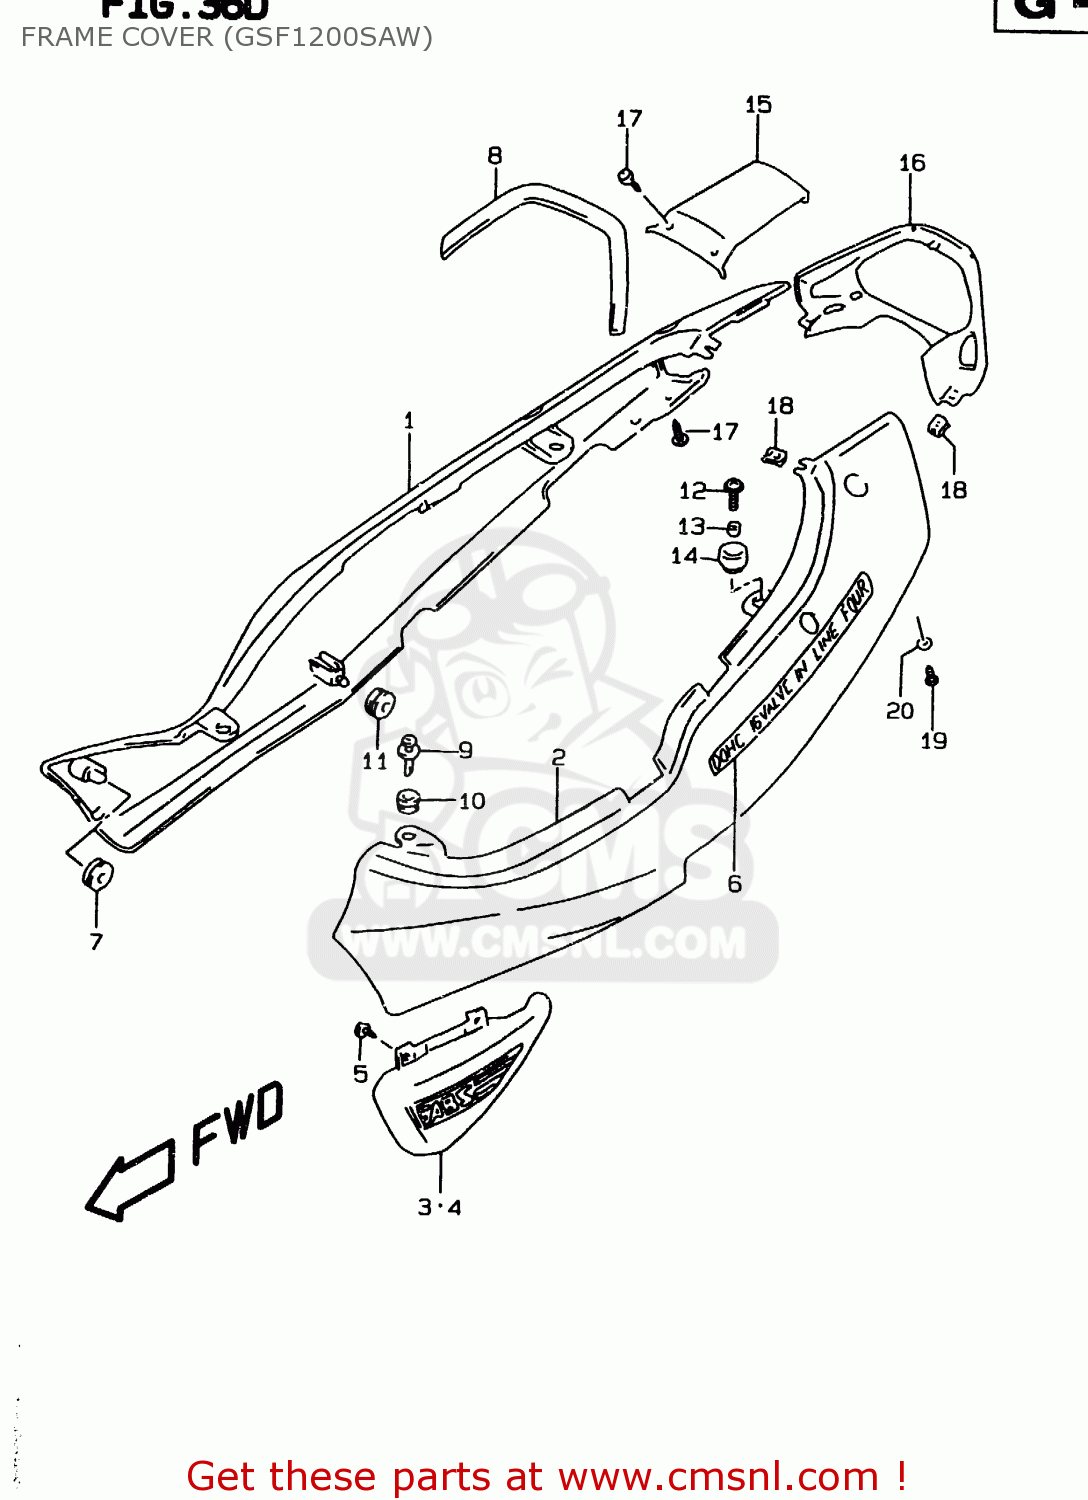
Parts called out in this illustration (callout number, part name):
1	COVER,FRAME,R(GREEN)
2	COVER,FRAME,L(BLACK)
3	COVER,FRAME LWR,R
4	COVER,FRAME LWR,L
5	SCREW
6	EMBLEM,FRAME COVER
7	CUSHION,FRAME COVER FR
8	CUSHION,FRAME COVER UPR
9	CLIP
10	CUSHION
11	CUSHION
12	SCREW(6X20)
13	SPACER(6.5X10X9.4)
14	CUSHION
15	COVER,FRAME CTR
16	COVER,FRAME RR
17	SCREW
18	NUT
19	SCREW
20	WASHER(6.3X16X1.5)
